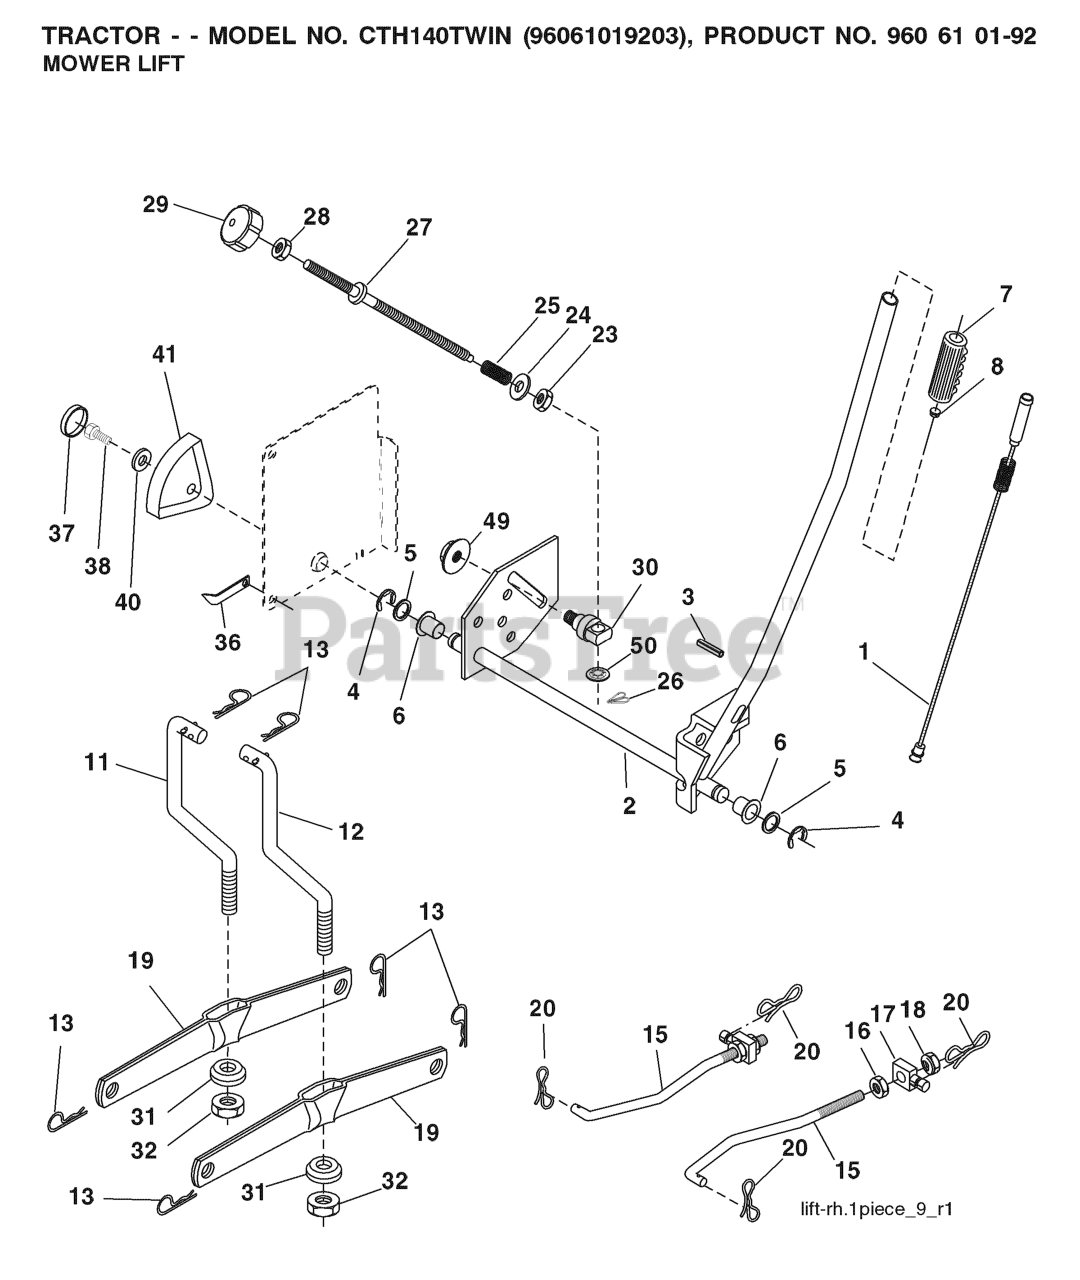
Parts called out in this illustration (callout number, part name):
1	PLUNGER.ASM.LIFT.LVR.BLK.17.32
2	SHAFT ASM R HANDLE
3	PIN GROOVE.
4	RETAINING RING LT
6	BEARING.NYLON
7	GRIP HANDLE
8	PLUNGER BUT KIT
11	LINK
12	LINK
13	RETAINER-SPRNG RB
15	LINK.SUSPENSION.FRONT
16	NUT.HEX.JAM.1/2-13
18	NUT.LK.W/WSH.1/2.
19	ARM.REAR.SUSPENSION
20	PIN.COTTER.7/16.BOW TI.
26	RETAINER CLIP
27	ROD ADJ LIFT
28	NUT
29	KNOB INF 3/8-16
31	BEARING.PIVOT.LIFT
32	NUT CROWNLOCK 3/8-24
36	POINTER, HEIGHT INDICATOR(2 2)
38	SCREW 5/16-18X1
41	HEIGHT INDICATOR
49	NUT
50	NUT PUSH M
